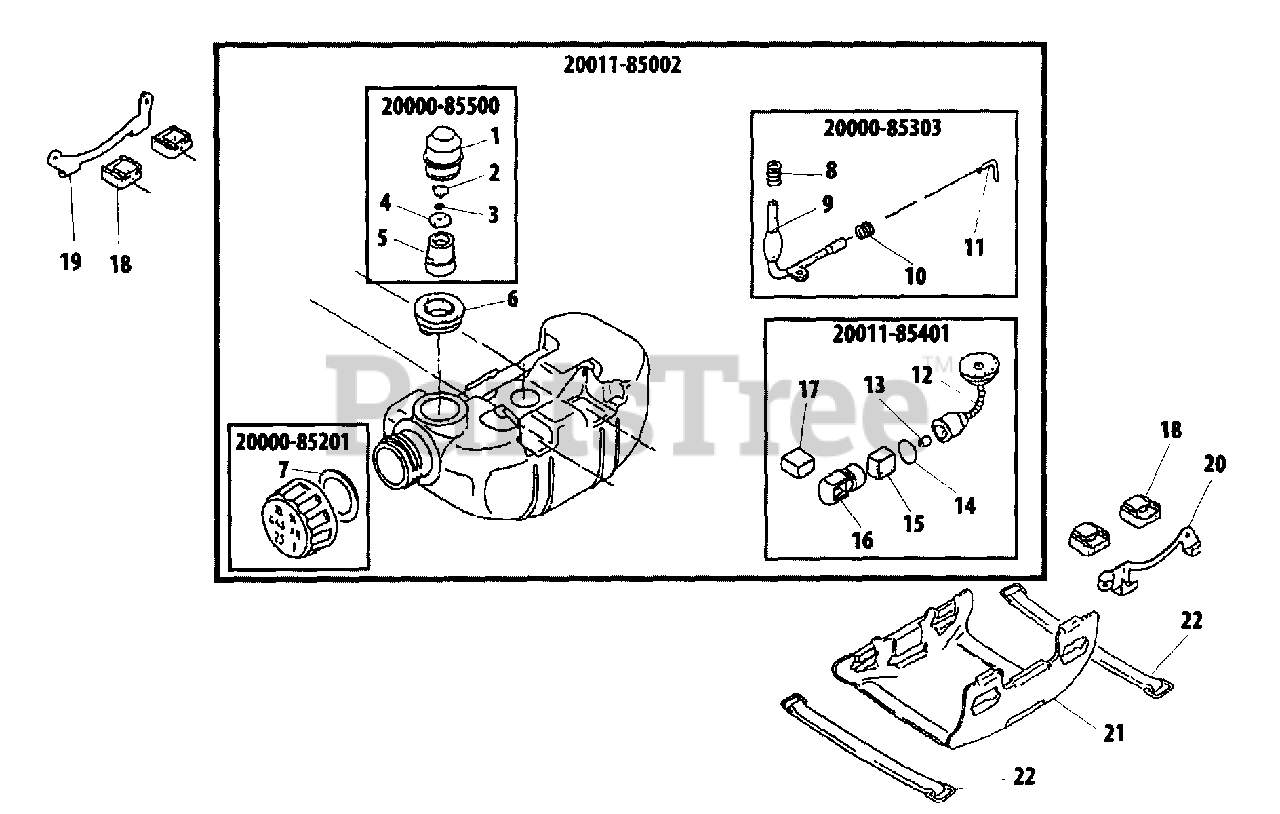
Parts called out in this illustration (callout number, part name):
1	CAP, VENT
2	VENT ASSY
3	WASHER
4	RETAINER
5	HOLDER, VENT
6	GROMMET, VENT
7	GASKET, FUEL CAP
8	CLAMP
9	PIPE, FUEL
10	CLIP
11	CONNECTOR, PIPE
12	PIPE, FUEL
13	VALVE, CHECK
14	CLIP
15	FILTER, FUEL - B
16	WEIGHT
17	FILTER, FUEL - A
18	CUSHION, FUEL TANK
19	BRACKET M
20	BRACKET S
21	GUARD, FUEL TANK
22	STRAP, FUEL TANK
20000-85201	CAP ASSY
20000-85303	PIPE ASSY, FUEL
20000-85500	VENT ASSY
20011-85002	TANK ASSY, FUEL
20011-85401	FILTER ASSY, FUEL
